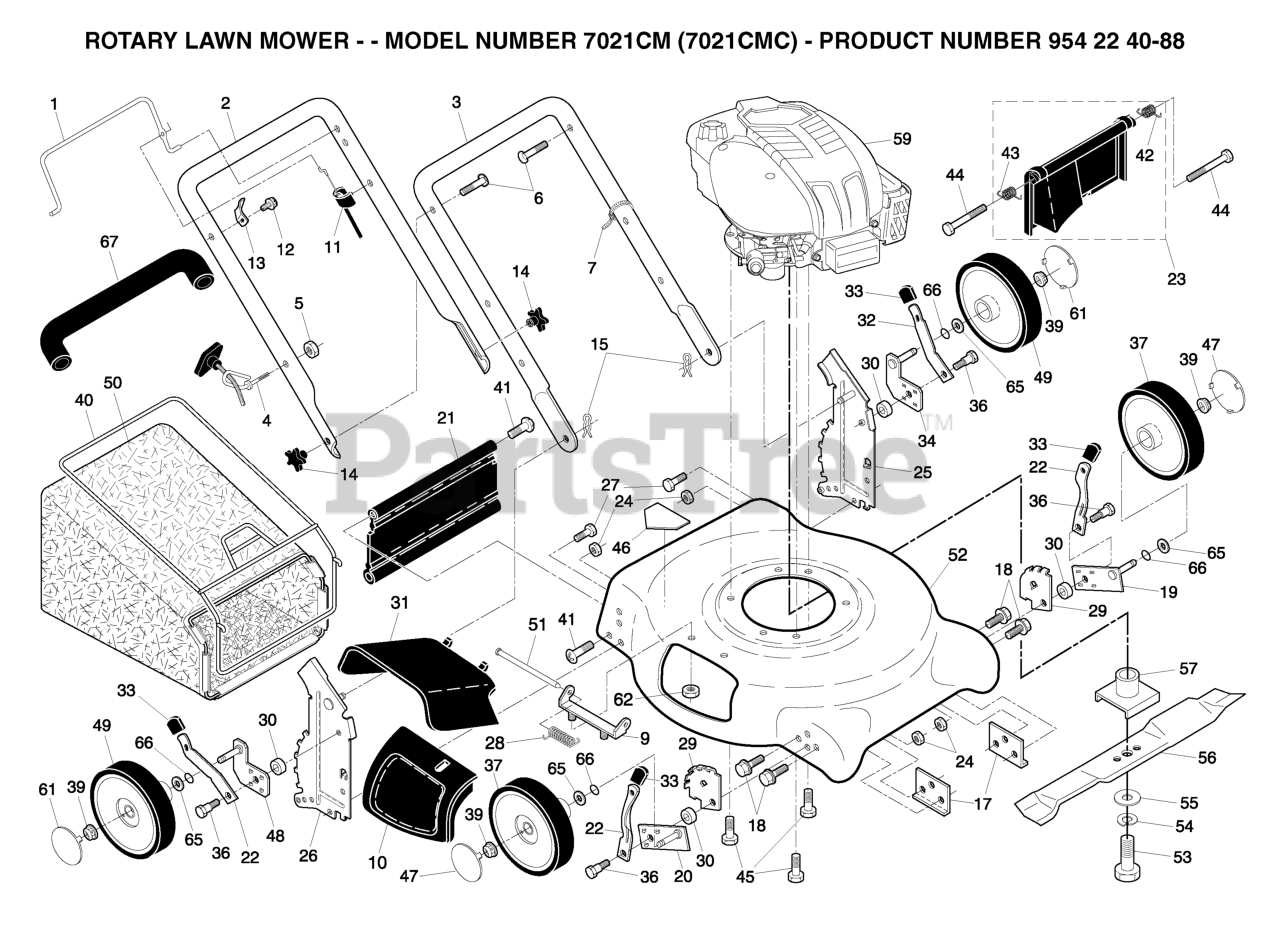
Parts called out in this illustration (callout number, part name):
3	HANDLE.LOWER.GREY
4	ROPE, GUIDE
5	NUT
6	BOLT, HANDLE 5/16-18X1.75
7	TIE GUIDE
9	BRACKET.ASM.HOUSING.EZ.MUL
11	ENGINE ZONE CONTROL CABLE
13	BRACKET
14	KNOB.HANDLE.STAR.HUSQ.GRAY
15	HAIRPIN COTTER
17	SUPPORT BRACKET
18	SCREW 1/4X20
19	AXLE ARM ASSY LF
20	AXLE ARM ASSY
22	REPL BY 532 1683-60
23	KIT.REAR.DOOR.21.DOMED.
24	NUT.CENTERLOCK.5/16-
25	HANDLE BRACKET ASSEMBLY, LEFT
26	HANDLE.BRKT.ASSY.RIGHT.BLACK
27	SCREW
28	TORSION SPRING
29	WHEEL BRACKET ADJUSTER
30	SPACER.34X1.38X.22
31	DEFLECTOR.CLIPPING.21.GREY
36	SHOULDER BOLT
37	WHEEL 8 X 2 BLACK BALL BEARING
39	HEX FLANGE LOCKNT
40	FRAME, GRASS BAG
41	HINGE SCREW
42	SPRING (LH)
43	SPRING (RH)
45	BOLT 3/8-16X1-1/8
46	DECAL HYT
47	HUBCAP
49	WHEEL.10X2.PR.HITRAC.BLACK
51	ROD.HINGE.COMBI-C
52	HOUSING ASSEMBLY
53	SCREW, HEX HD 3/8-24 X 1-3/8
54	LOCKWASHER
55	WASHER,HARDEN
56	BLADE.21.PUSH/RWGD/FWG
57	BLADE ADAPTER
62	LOCKNUT.NYLOC.1/4-20
65	WASHER.FLAT.1/2
66	O-RING
67	GRIP.HANDLE.FOAM
